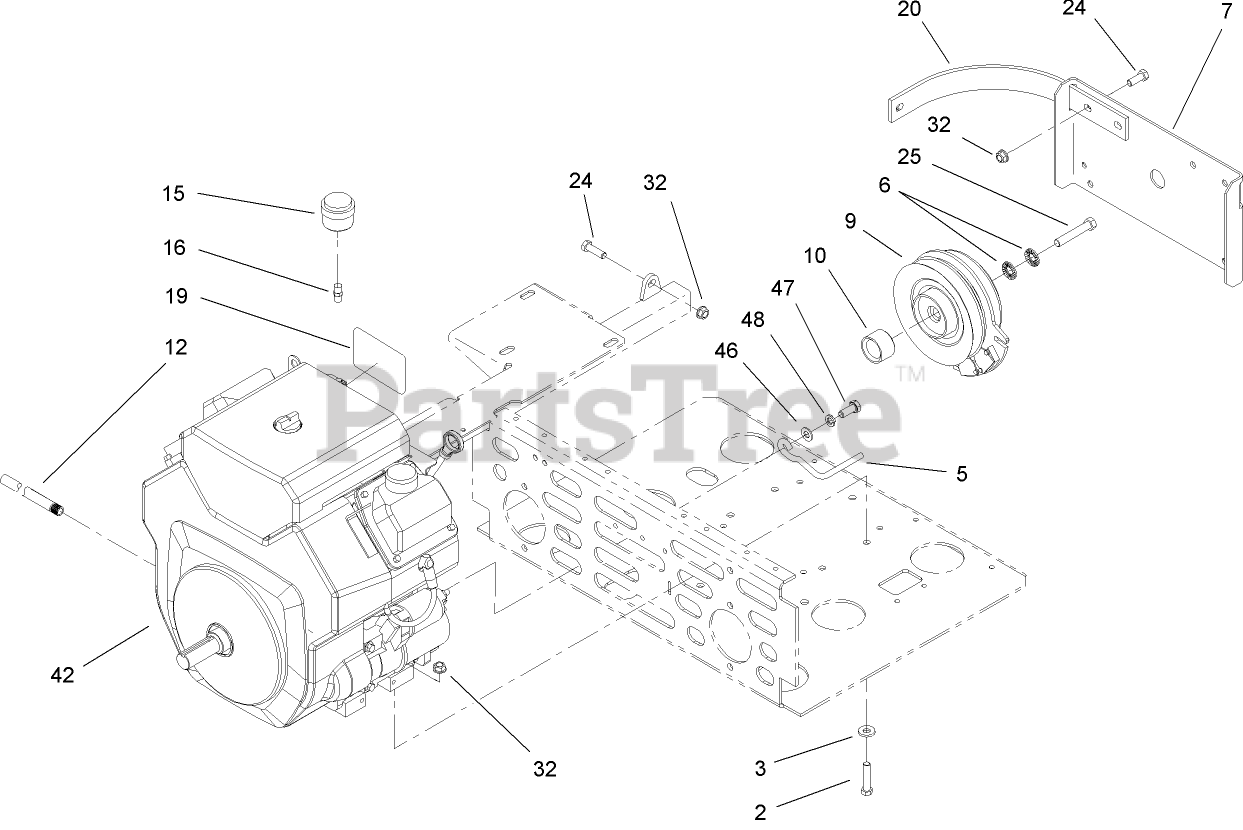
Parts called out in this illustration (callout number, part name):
2	SCREW-HH
3	WASHER-BELLEVILLE
5	ROD-BELT
6	WASHER-SPRING
7	GUARD-CLUTCH
9	CLUTCH
10	SPACER-CLUTCH
12	TUBE-DRAIN, OIL
15	INDICATOR-FILTER, AIR
16	ADAPTER-INDICATOR
20	STRAP-GUARD
24	SCREW-HH
25	SCREW-HH
32	NUT-HHF, WHIZ
46	WASHER-FLAT
47	SCREW-HH
48	WASHER-BELLEVILLE
